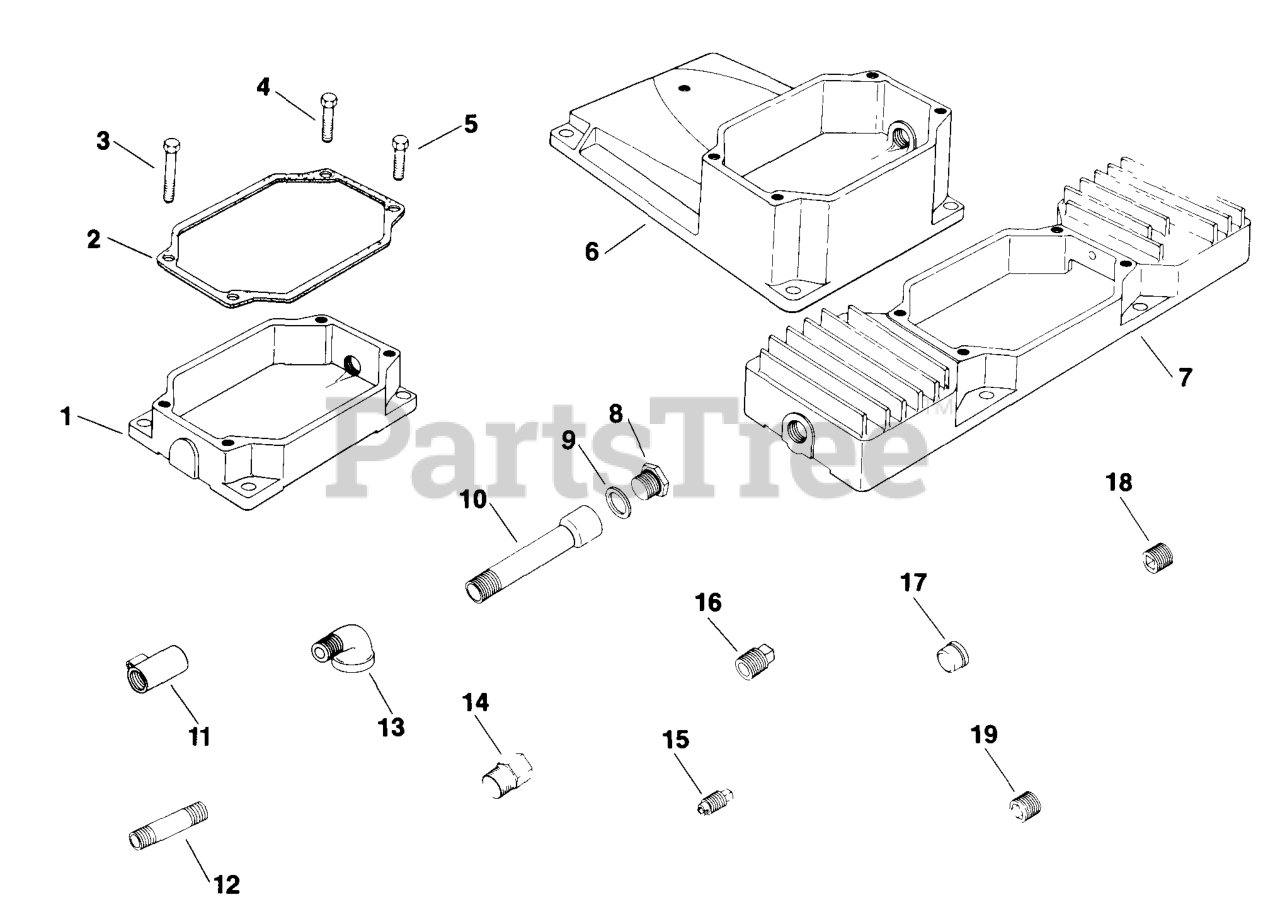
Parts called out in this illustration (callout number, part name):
1	PAN - (#DSC)
16	PLUG,PIPE 1/2 NPTF SQUARE HD USE 25 139 61-S
19	PLUG,PIPE 1/2 NPTF SQUARE HD USE 25 139 54-S
